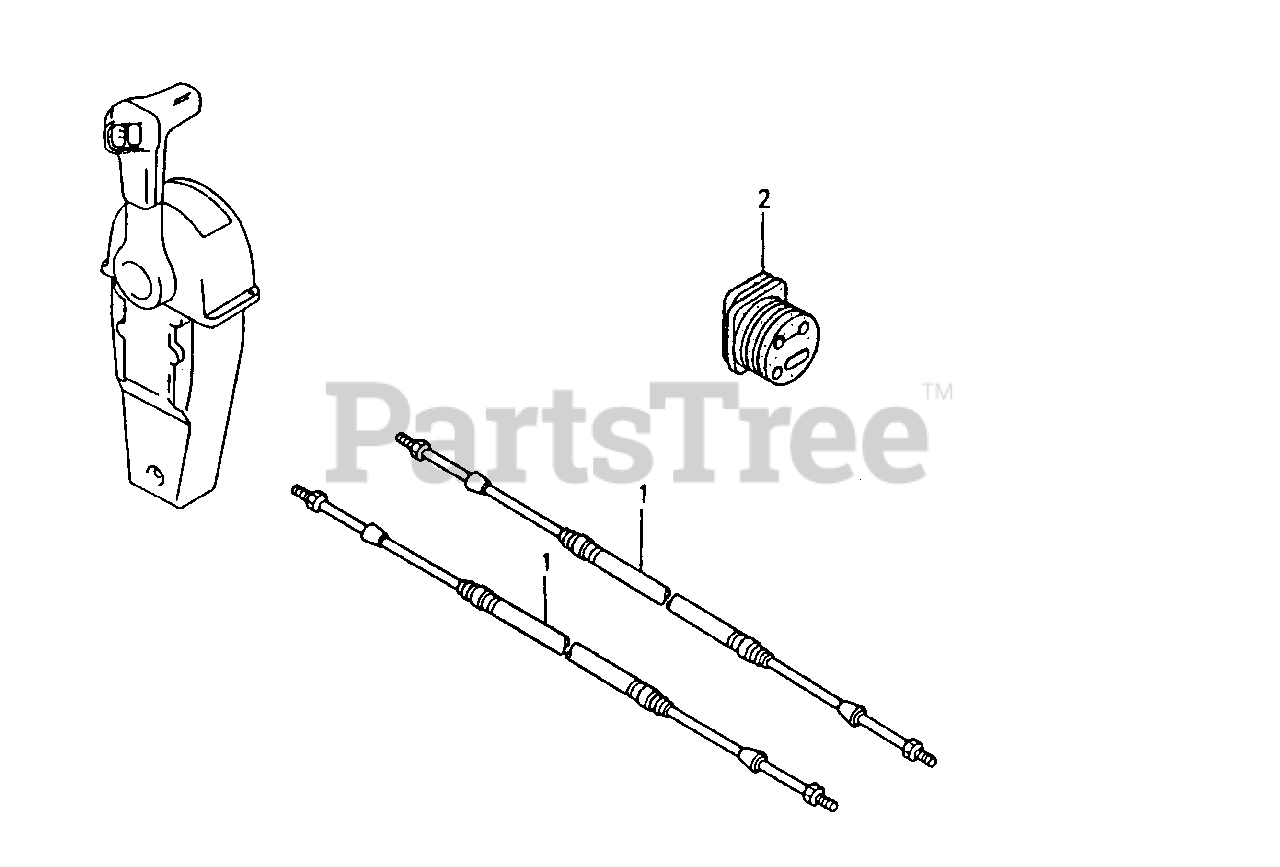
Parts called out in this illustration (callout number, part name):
1	CABLE ASSY., PUSH-PULL (33C-5FT)
1	CABLE ASSY., PUSH-PULL (33C-6FT)
1	CABLE ASSY., PUSH-PULL (33C-7FT)
1	CABLE ASSY., PUSH-PULL (33C-8FT)
1	CABLE ASSY., PUSH-PULL (33C-9FT)
1	CABLE ASSY., PUSH-PULL (33C-10FT)
1	CABLE ASSY., PUSH-PULL (33C-11FT)
1	CABLE ASSY., PUSH-PULL (33C-12FT)
1	CABLE ASSY., PUSH-PULL (33C-13FT)
1	CABLE ASSY., PUSH-PULL (33C-14FT)
1	CABLE ASSY., PUSH-PULL (33C-15FT)
1	CABLE ASSY., PUSH-PULL (33C-16FT)
1	CABLE ASSY., PUSH-PULL (33C-17FT)
1	CABLE ASSY., PUSH-PULL (33C-18FT)
1	CABLE ASSY., PUSH-PULL (33C-19FT)
1	CABLE ASSY., PUSH-PULL (33C-20FT)
1	CABLE ASSY., PUSH-PULL (33C-21FT)
1	CABLE ASSY., PUSH-PULL (33C-22FT)
1	CABLE ASSY., PUSH-PULL (33C-23FT)
1	CABLE ASSY., PUSH-PULL (33C-24FT)
1	CABLE ASSY., PUSH-PULL (33C-25FT)
1	CABLE ASSY., PUSH-PULL (33C-26FT)
1	CABLE ASSY., PUSH-PULL (33C-27FT)
1	CABLE ASSY., PUSH-PULL (33C-28FT)
1	CABLE ASSY., PUSH-PULL (33C-29FT)
1	CABLE ASSY., PUSH-PULL (33C-30FT)
1	CABLE ASSY., PUSH-PULL (33C-31FT)
1	CABLE ASSY., PUSH-PULL (33C-32FT)
2	GROMMET, CASE (LOWER) (B)
